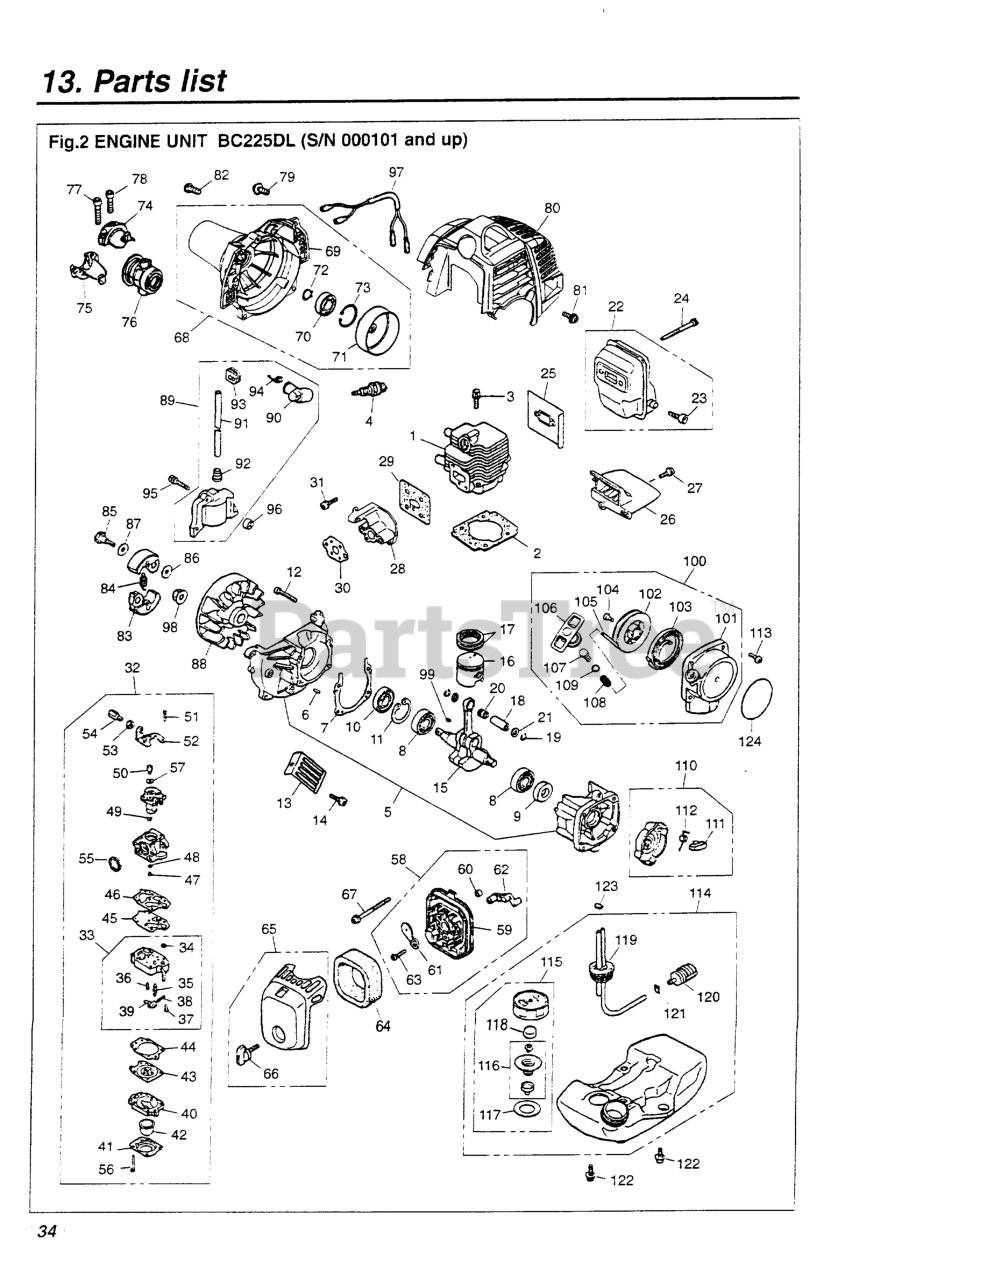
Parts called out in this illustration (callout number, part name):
1	CYLINDER
2	GASKET, BASE (RPLS -12212)
3	BOLT, M5 X 22
5	CRANKCASE
6	PIN
7	GASKET (RPLS -21140)
8	BEARING
9	SEAL, OIL (RPLS 1100-21210)
10	SEAL, OIL (RPLS 1140-21220)
11	RING, SNAP, M28 x 1.2
12	BOLT, M5 X 30
14	SCREW,M5 X 14 (RPLS 1400-15510
15	CRANKSHAFT (RPLS 1850-42000)
16	PISTON (REPLACES 1140-41110)
17	RING, PISTON (RPLS 1850-41210)
18	PIN, PISTON 5x8x26
19	RING, SNAP (RPLS 1101-41320)
20	BEARING (RPLS 1140-41330)
21	WASHER
22	MUFFER ASSEMBLY
23	ARRESTER (RPLS 5850-15140)
24	BOLT, M5 x 50
25	GASKET
26	PLATE, MUFFLER (RPLS -15220)
27	SCREW, M4 X 16
28	INSULATOR
29	GASKET (RPLS -13120)
30	GASKET (REPLACES -13130)
31	SCREW, M5X20 (RPLS.1400-75510)
32	CARBURETOR
33	BODY, PUMP
35	VALVE, INLET
36	SPRING, METERING LEVER
37	SCREW, METERING LEVER PIN
38	PIN, METERING LEVER
39	LEVER
40	BODY, PURGE
41	COVER, PUMP
42	PUMP, PRIMING
43	DIAPHRAGM (USE 4810-81260)
44	GASKET, DIAPHRAGM
45	DIAPHRAGM
46	GASKET, PUMP
47	JET
48	RING, O
49	RING
50	SWIVEL
51	SCREW
53	NUT, CABLE ADJUSTER
54	SCREW, CABLE ADJUSTER
55	RING, PACKING
56	SCREW
57	WASHER
58	BODY ASSEMBLY
60	SLEEVE
61	PLATE, CHOKE
62	LEVER, CHOKE
63	SCREW (REPLACES 50030272)
64	ELEMENT
65	COVER ASSEMBLY
66	KNOB (RPLS -82220)
67	SCREW, M5 x 60
69	HOUSING
72	RING, SNAP (RPLS 3130-13270)
73	RING, SNAP, M28 x 1.2
75	BRACKET (B)
77	BOLT, M5 X 22
78	BOLT, M5 X 10
79	SCREW, M5X20 (RPLS.1400-75510)
80	COVER, ENGINE (USE -32111)
82	SCREW,M5 X 14 (RPLS 1400-15510
83	SHOE (RPLS 1100-51114)
84	SPRING
85	BOLT
86	WASHER, FLAT (USE 182303)
88	ROTOR
89	COIL-A (USE T1700-71201)
90	CAP
91	CORD
92	CAP
93	GROMMET
94	SPRING
95	BOLT
96	SPACER
97	CORD COMP
99	KEY
100	RECOIL ASSEMBLY
101	CASE
102	REEL
103	SPRING, SPIRAL
104	SCREW (RPLS -75150)
105	ROPE
106	KNOB
107	COLLAR
108	SPRING
109	WASHER
110	PULLEY ASSY (RPLS -75210)
111	RATCHET (RPLS 1850-75220)
112	SPRING, RETURN
115	5607-85201 (CAP ASSY.)
116	HOLDER - A (RPLS 5601-85230)
117	PACKING
118	FILTER
119	PIPE COMPLETE
120	FILTER (RPLS 1850-85300)
121	CLIP (REPLACES 2841-31280)
122	SCREW W/ WASHER
123	CLIP
124	LABEL, RECOIL
